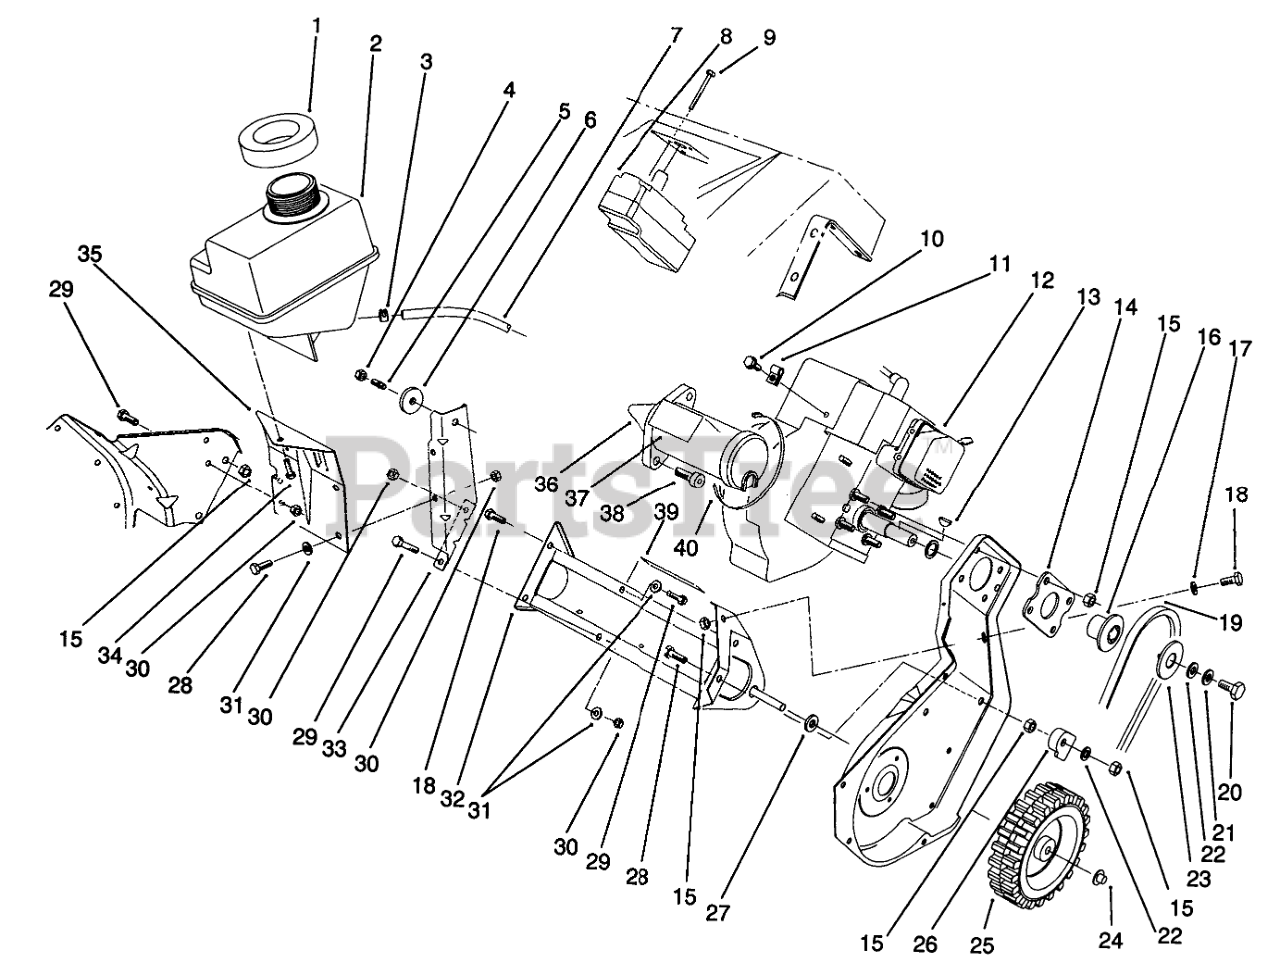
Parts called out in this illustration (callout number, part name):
1	SEAL-FOAM
2	Tank-Gas
3	Clamp
4	NUT-LOCK, NI
6	WASHER-SUPPORT, ENGINE
7	LINE-FUEL
8	Starter Switch Assembly
9	SCREW-PLASTITE
10	SCREW-HWH
11	CABLE CLAMP
13	KEY-WOODRUFF
14	Plate Engine
15	NUT-LOCK, NI
16	Hub-HALF SHEAVE
17	WASHER-PLAIN
18	SCREW-HH
19	Belt-Drive
20	SCREW-HH
21	WASHER-BELLEVILLE
22	WASHER-FLAT
23	CAP-HALF SHEAVE
24	RETAINER-PUSH ON
25	WHEEL
26	Guide-Cable
27	SPACER-PLASTIC
28	SCREW-HH
29	SCREW-HH
30	NUT-LOCK, NI
31	WASHER-FLAT
32	Frame Assembly
33	Support-Engine
34	SCREW-SHWH, THREAD FORMING
35	Bracket-Fuel Tank
36	Starter Motor Assembly
37	Decal
38	Screw-Thread Forming
39	Decal
40	TIE-CABLE
